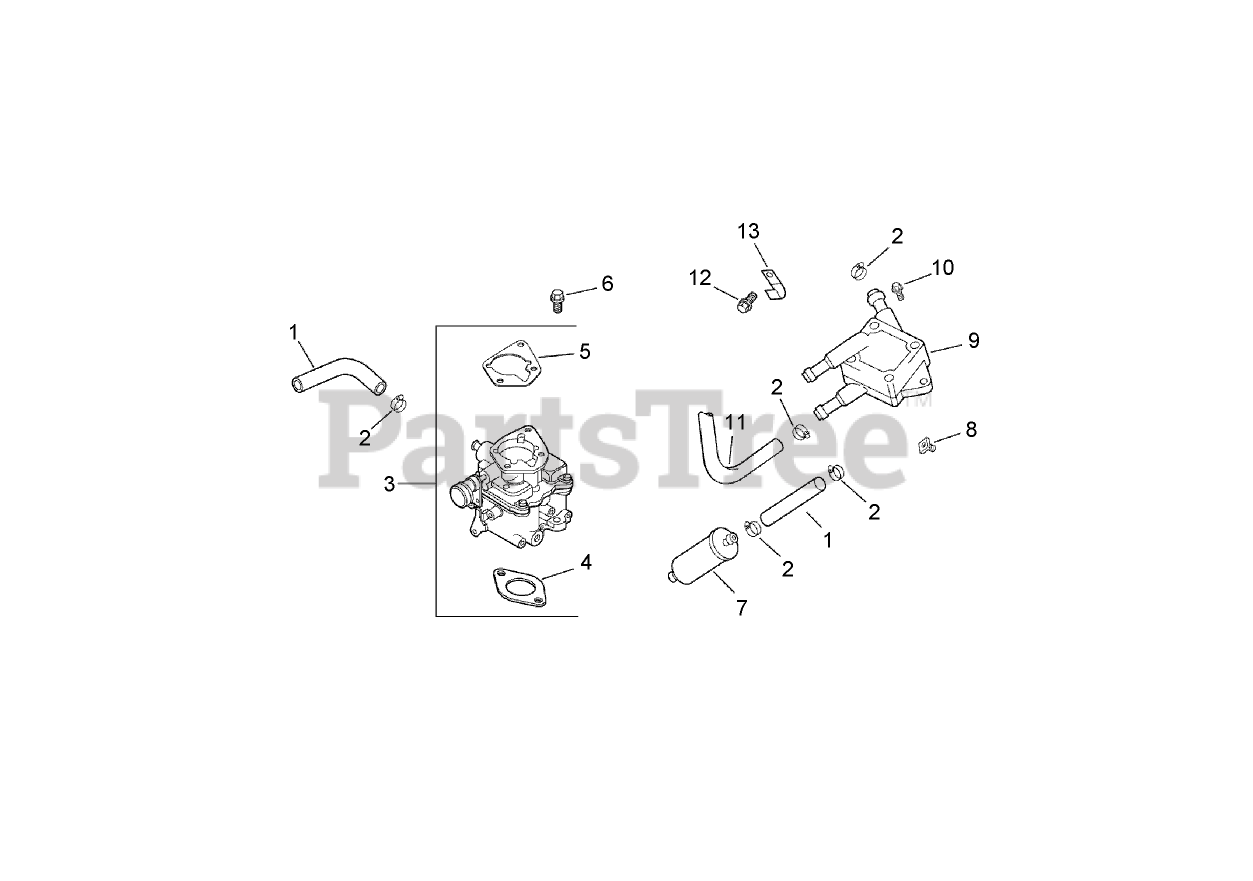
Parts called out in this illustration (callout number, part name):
1	Line-Fuel (9.5)
2	CLAMP-HOSE, SPRING (1/2)
3	Carburetor Kit (Includes 4, 5)
4	GASKET-BASE, AIR CLEANER
5	Gasket-Carburetor
6	Screw-HF (M6x1.0x25)
7	FILTER-FUEL
8	Nut-Plastic
9	PUMP-FUEL
10	SCREW-TAP (M6X1.7X18)
11	Line-Fuel, Flexible (15.5)
12	Screw-HF (M6x1.0x12)
13	CLIP-CABLE
